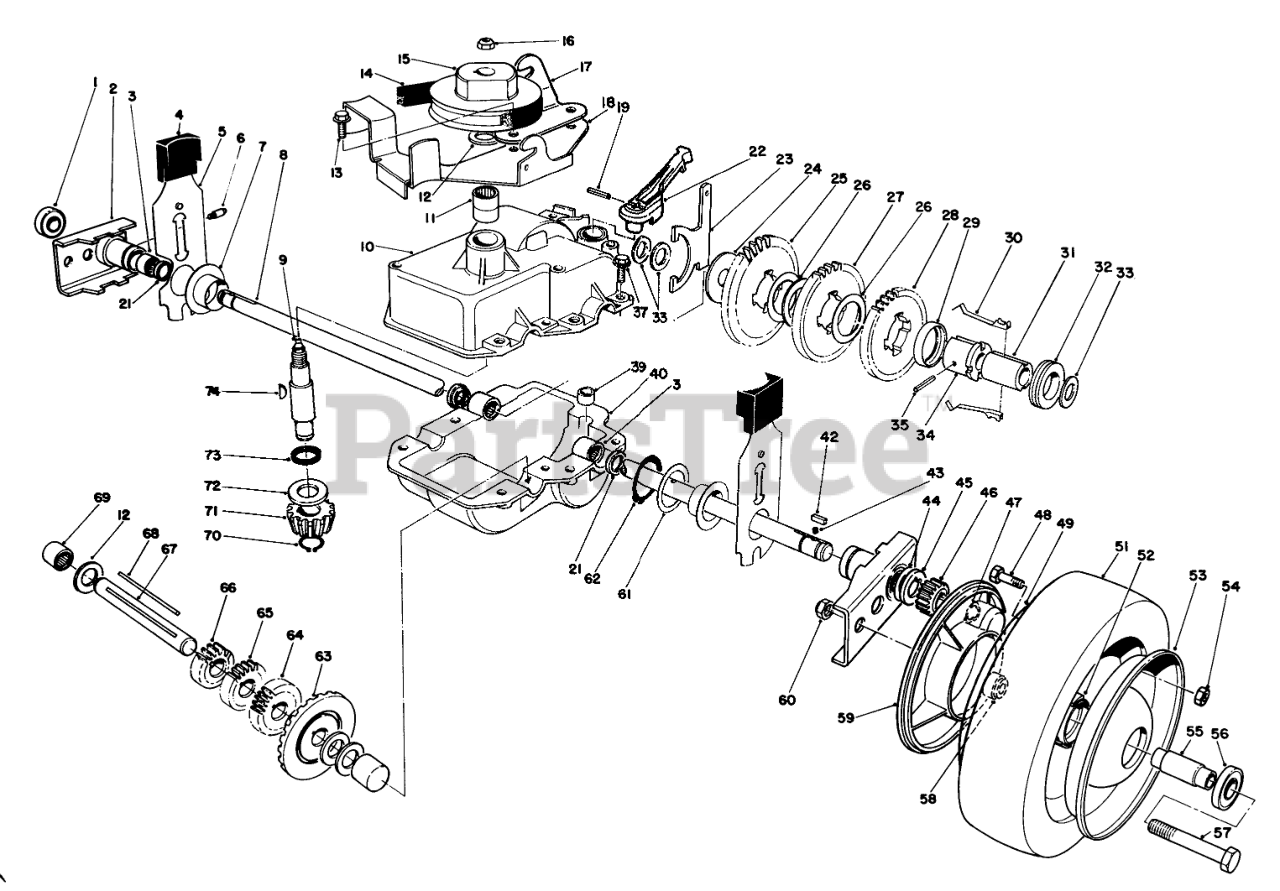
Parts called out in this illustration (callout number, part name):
1	BEARING-WHEEL
2	Pivot Arm Assembly (Incl. Ref. #1, 3, 6 & 21)
3	BEARING-ROLLER
4	KNOB-ARM
5	REAR SPRING ARM ASM
6	FITTING-GREASE
7	CAP-END
8	SHAFT-OUTPUT
9	INPUT SHAFT ASM
10	Upper Case Assembly (Incl. Ref. #11 & 73)
11	BEARING-NEEDLE
12	WASHER-THRUST
13	SCREW
14	V-BELT
15	PULLEY
16	NUT-HEX
17	Bracket-Traction Engage
18	Belt Guide Bracket
19	PIN-COIL
21	SEAL-OIL
22	LEVER-SHIFT
23	YOKE-SHIFT
24	WASHER
26	WASHER
27	GEAR-42T
28	GEAR-38T
29	RETAINER-KEY
30	KEY-SHIFT
31	SLEEVE
32	COLLAR-SHIFT
33	WASHER-PLAIN
34	SLEEVE-GEAR
35	PIN-GROOVE
37	SCREW-HWHTF
39	BUSHING-YOKE
40	CASE-GEAR, LOWER
42	KEY RECTANGULAR
43	SPRING-COMPRESSION
44	WASHER-THRUST, OUTER
45	WASHER-THRUST, OUTER
46	GEAR-PINION
47	RING-RETAINING
48	SCREW-HH
49	Wheel-Half
52	HUB-BEARING
53	Wheel-Half
54	NUT-LOCK, NI
55	SPACER-BEARING
56	BEARING-WHEEL
57	SCREW-HH
58	SPACER-COVER, WHEEL
59	COVER-WHEEL
60	NUT-LOCK, CONE
61	WASHER
62	RING-RETAINING
63	GEAR-BEVEL
64	GEAR-18T
65	GEAR-14T
66	GEAR-12T
67	SHAFT-INTERMEDIATE
69	BEARING-NEEDLE, CLOSED
70	RING-RETAINING
71	PINION-BEVEL
72	WASHER-THRUST
74	KEY-WOODRUFF
